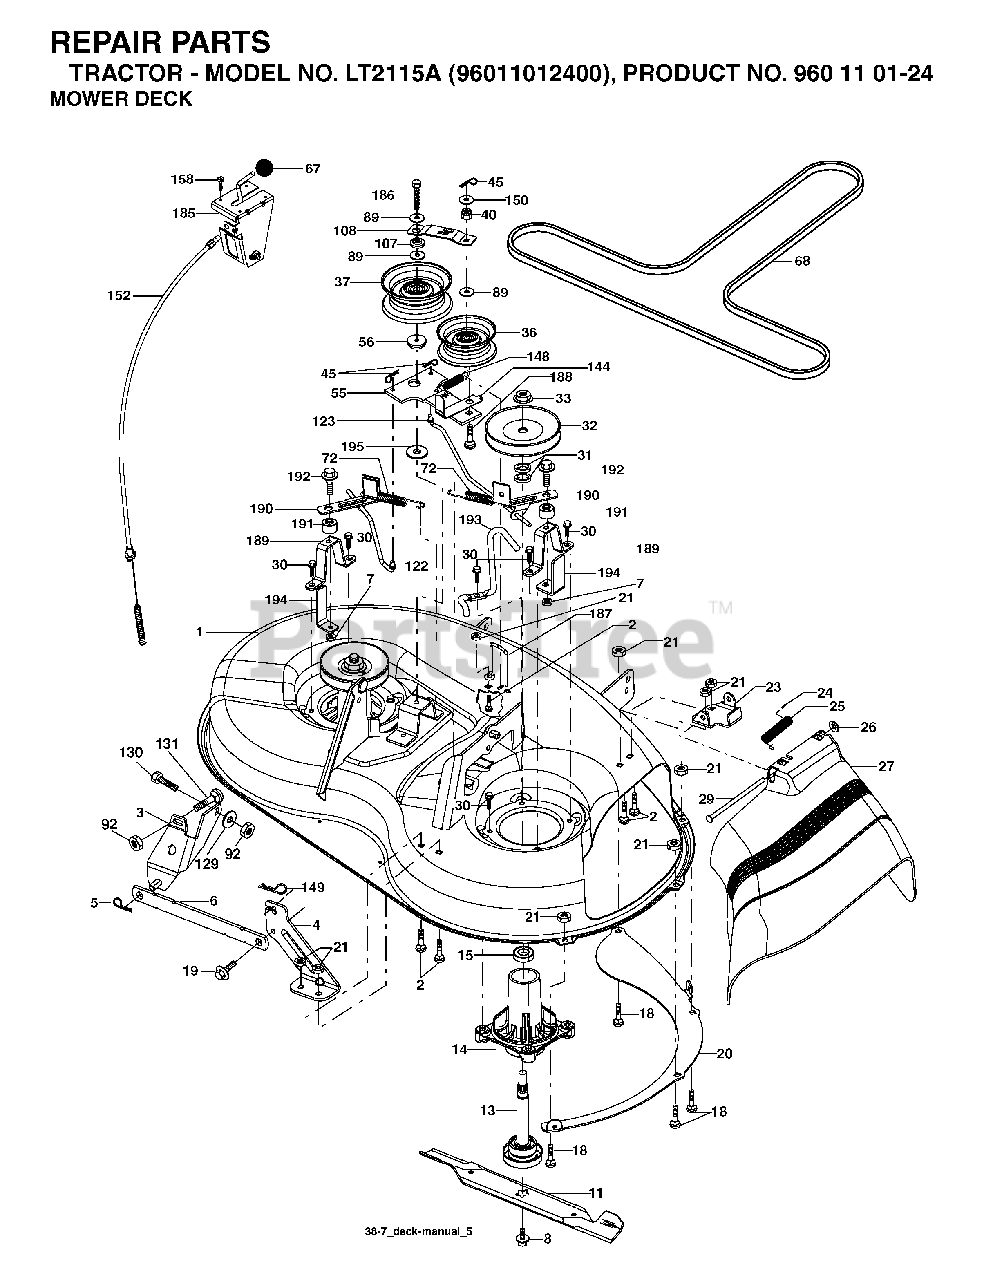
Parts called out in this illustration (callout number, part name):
1	DECK.WELDMENT.38"2005
2	BOLT
3	BRKT ASM SWAY BAR
4	BRACKET DECK SWAY BAR 38"/42"
5	RETAINER-SPRNG RB
6	BAR SWAY DECK
7	NUT.71038.31-18.HEX.NYLOCK
8	BOLT.WASHER.ASM.7/16-2
11	BLADE 38" PREMIUM
13	SHAFT.ASM.MDRL.N/GREASE.38
14	HOUSING MANDREL
18	BOLT
19	BOLT SHD 5/16-18
20	BAFFLE VORTEX
21	LOCKNUT
23	BRKT.DEFLECTOR.38"2005+
24	CAP-SLEEVE LT
25	SPRING.TORSION.DEFLECT
26	NUT PUSH M
29	ROD.HINGE
30	SCREW, WASHER HEAD
31	WASHER.SPACER.MANDREL
32	PULLEY MANDREL
33	NUT.FLANGE.LOCK.TOP
36	FLAT IDLER PULLEY
37	PULLEY.IDLER.FLAT.UNPLATED
40	LOCKNUT
45	RETAINER M
55	IDLER ARM
56	SPACER.RETAINER.MOWER
67	KNOB T (3/8 HOLE)
68	V-BELT.MOWER.38"2005+
72	SPRING.BRAKE.RETURN.38"
89	WASHER
92	NUT
107	SPACER.IDLER.ARM
108	STIFFENER.IDLER.ARM
129	WASHER
131	BOLT D
144	KEEPER BELT
148	IDLER RETURN SPRING
149	SPRING.RETAINER.YELLOW.ZINC
150	WASHER LT
152	CABLE.CLUTCH.38".SERVICE
158	SCREW
185	HEAD ASM. CABLE CLUTCH
186	SCREW.HXWSH.3/8
187	KEEPER BELT
188	BOLT, CARRIAGE IDLER
189	STAND, BRAKE
190	ARM, BRAKE
191	SPACER, BRAKE
192	BOLT/WASHER ASM 5/16-18
193	KEEPER BELT RH MANDREL
194	GUARD BRAKE
195	WASHER 12/32X2X10GA
